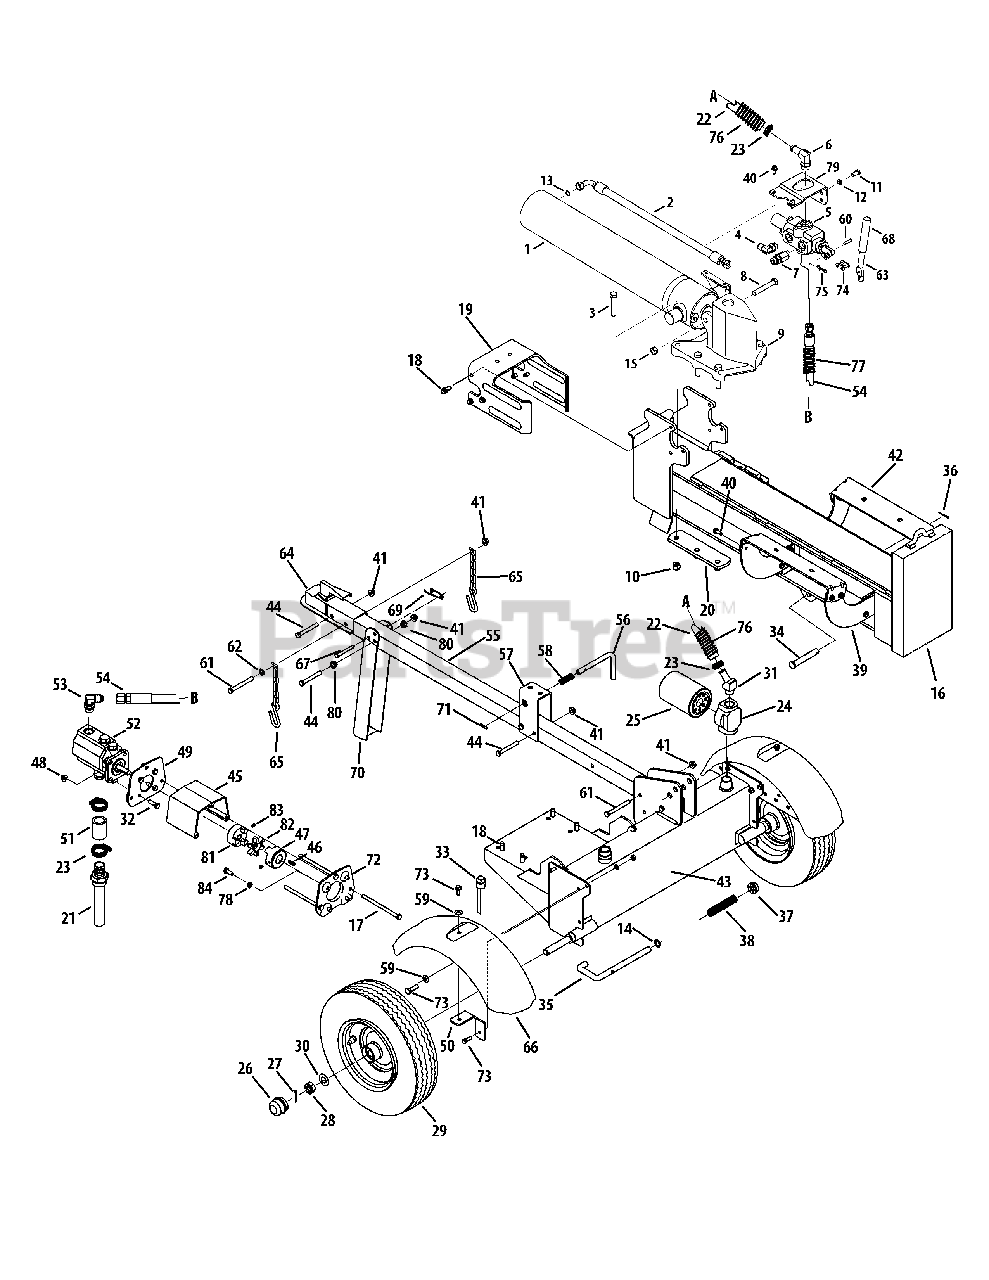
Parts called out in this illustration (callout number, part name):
1	Hydraulic Cylinder
2	Hydraulic Tube
3	Hex Cap Screw, 1/2-20 x 2.75
4	90 Degree Solid Adapter
5	Control Valve
6	Return Elbow
7	Nipple Pipe, 1/2-14
8	Hex Cap Screw, 1/2-13 x 3.25
9	Wedge Assembly
10	Hex Lock Nut, 1/2-20
11	Hex Cap Screw, 3/8-16 x .75
12	Lock Washer, 3/8
13	O-Ring, .489 ID x .070 Dia.
14	Flat Washer, .635 x.93 x.06
15	Hex Lock Nut, 1/2-13
16	Beam Assembly
17	Hex Screw, 5/16-18 x 4.00
18	Self Tapping Screw, 3/8-16 x 1.0
19	Dislodger Bracket
20	Back Plate
21	Inlet Filter
22	Return Hose, 3/4 x 44
23	Hose Clamp, 5/8
24	Filter Housing
25	Oil Filter
26	Hub Cap
27	Cotter Pin
28	Slotted Nut, 3/4-16
29	Complete Wheel Assembly
29	Dust Seal
29	Roller Bearing
30	Flat Washer, .760 x.500
31	Hydraulic Fitting, 1 1/16 Orb x .75
32	Hex Screw, 5/16-18 x 1.00
33	Vented Dipstick
34	Clevis Pin
35	Lock Rod
36	Cotter Pin
37	Push Cap
38	Compression Spring
39	Log Tray Bracket
40	Hex Washer Screw, 5/16-18 x .750
41	Flange Lock Nut, 3/8-16
43	Frame Assembly - MTD Engine
44	Hex Bolt, 3/8-16 x 3
45	Coupling Shield
46	Square Key, 3/16" x .75
47	Coupling, .750
48	Flange Lock Nut, 5/16-18
49	Rear Coupling Support Bracket
50	Fender Mounting Bracket
52	Gear Pump
53	45 Degree Elbow Fitting
54	High Pressure Hydraulic Hose
55	Tongue Assembly
56	Latch Rod
58	Compression Spring
59	Flat Washer
60	Clevis Pin
61	Hex Cap Screw, 3/8-16 x 3.50
62	Flat Washer, .375 x.738 x.063
63	Hydraulic Valve Control
64	Hitch Coupling Assembly
66	Fender
67	Clevis Pin
69	Spring Pin
70	Jack Stand
71	Spiral Pin
72	Front Coupling Support Bracket
73	Self-Tapping Screw, 5/16-18 x 1.00
74	Valve Handle Link
75	Cotter Pin, Bow Tie
76	Hose Guard, 48"
77	Hose Guard, 44"
78	Lock Washer, 5/16
79	Outer Valve Bracket
80	Plastic Bushing, .380 ID
81	Coupling, .500
82	Spider Bushing
83	Set Screws
84	Hex Cap Screw, 5/16-24 x .75
